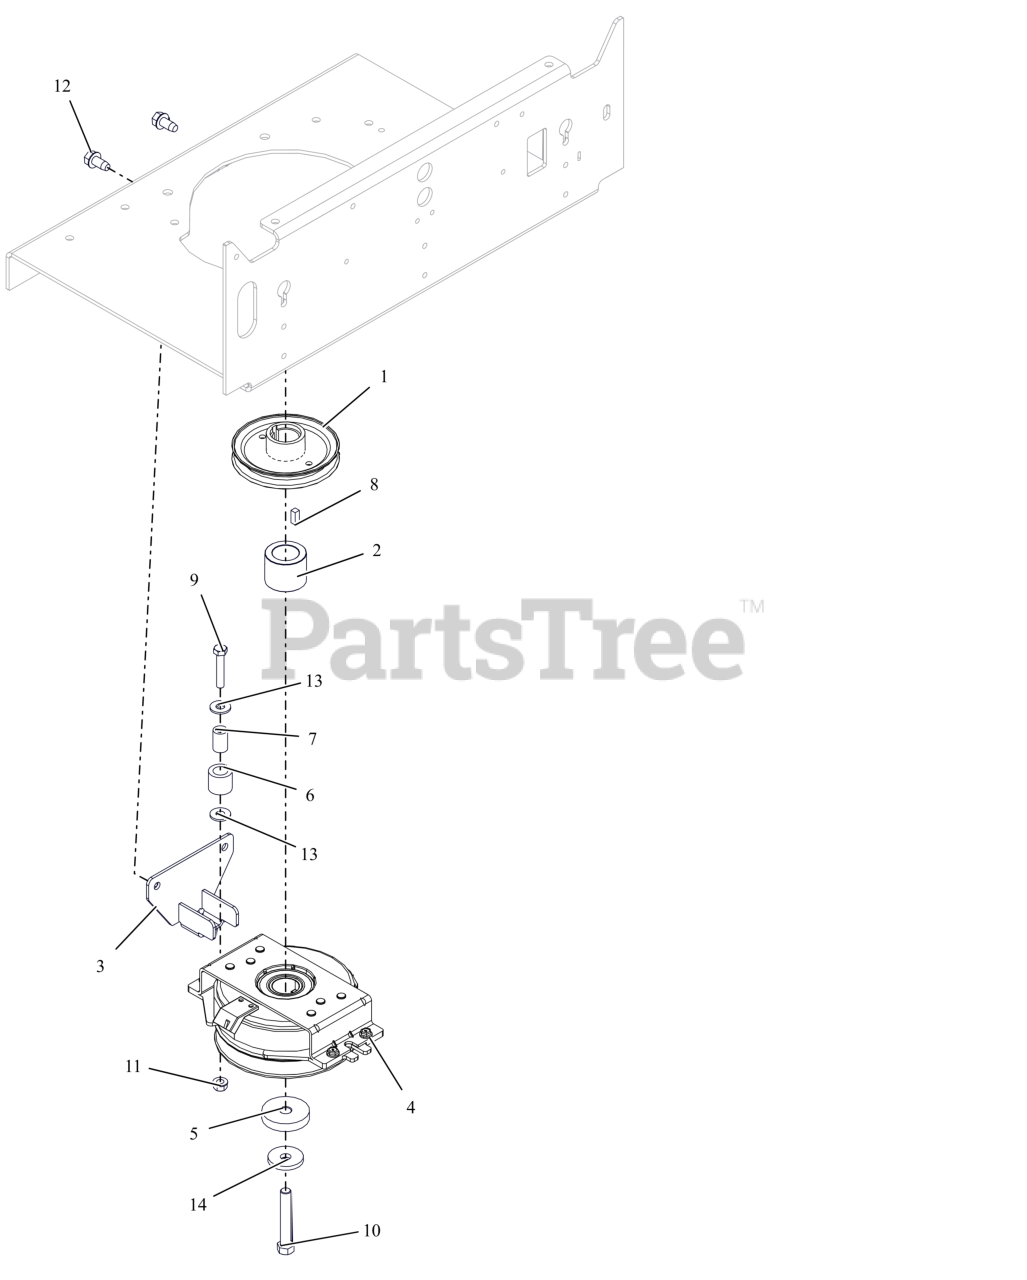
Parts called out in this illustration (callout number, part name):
1	PULLEY, 4.50 OD X 1.127 ENGINE
2	SPACER, 1.125 X 1.75 X 1.40
3	BRKT, CLUTCH STOP (BLACK)
4	CLUTCH, OGURA GT2.75-BBO1
5	SPACER, .450X2.00X.396
6	BUMPER,RUBBER .62X1.0X.88 LG
7	BUSH.,S.391X.622X.950 ST
8	KEY-SQ .25X.625X.25 SAE 8630
9	BLT, HEX .31-18X1.75 G5 ZCC
10	BLT, HEX 0.4375-20X2.75 G8 ZCC NT
11	NUT,LK-CTR-FLG .31-18 GF ZCC
12	SCR,TAP .375-16X.75 HWH TR ZCC
13	WSHR,FLT .375X.875X.083 ZCC
14	WASHER, 7/16" SPRING DISK
